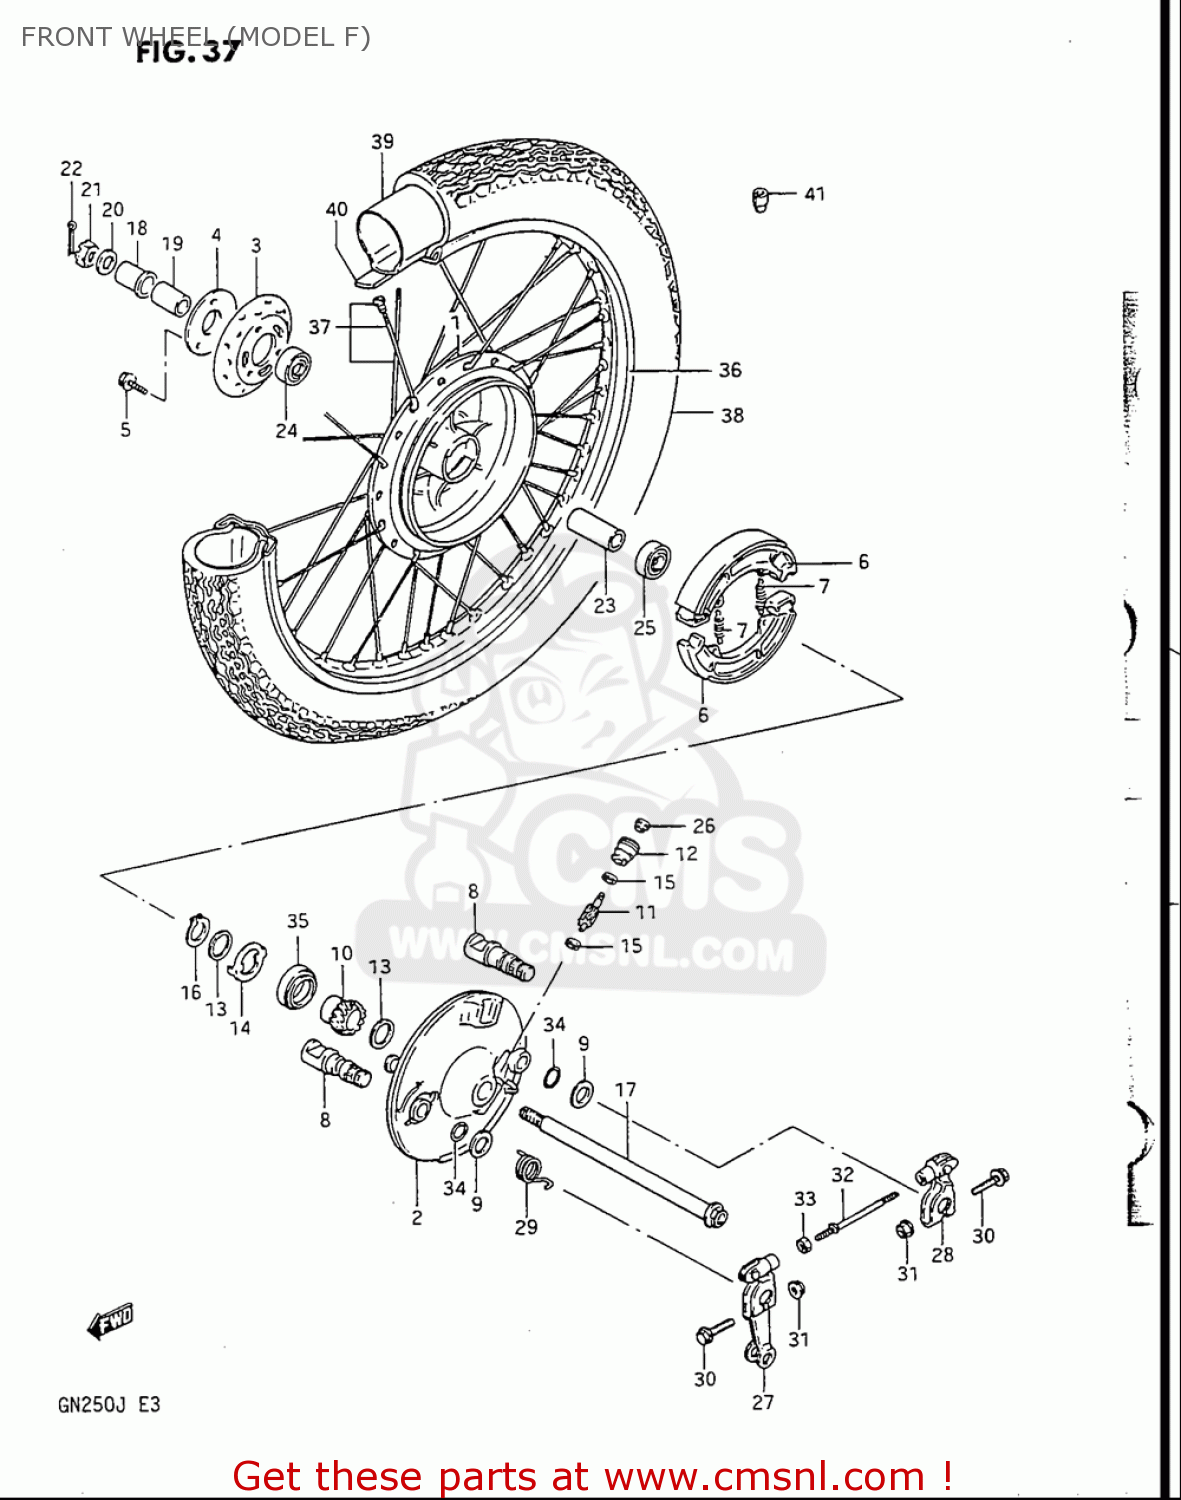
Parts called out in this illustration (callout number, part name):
5	BOLT
6	SHOE SET,BRAKE
7	SPRING
8	CAM,BRAKE
9	WASHER(15.5X24X1.6)
10	GEAR,SPEEDOMETER
11	PINION,SPEEDOMETER
12	BUSHING,SPEEDOMETER PINION
13	WASHER(22.5X27X1)
14	DRIVER,SPEEDOMETER GEAR
15	WASHER(5.1X9X0.4)
16	CIRCLIP
19	SPACER(12X20X34.5)
20	WASHER
21	NUT 12MM
22	PIN
23	SPACER(12.5X19X52)
24	BEARING (12X32X10)
25	BEARING
26	SEAL,OIL(6X10X3)
28	LEVER, BRAKE CAM NO.2
30	BOLT
31	NUT
32	ROD,BRAKE CAM LEVER CONNECTION
33	NUT
34	O RING(D:2.4,ID:14.8)
35	SEAL,OIL(26X38X4)
37	SPOKE SET,FRONT
38	TIRE,FRONT 3.00 S18
39	TUBE ASSY,WHEEL INNER
40	PROTECTOR,INNER TUBE
41	BALANCER,WHEEL (B)
